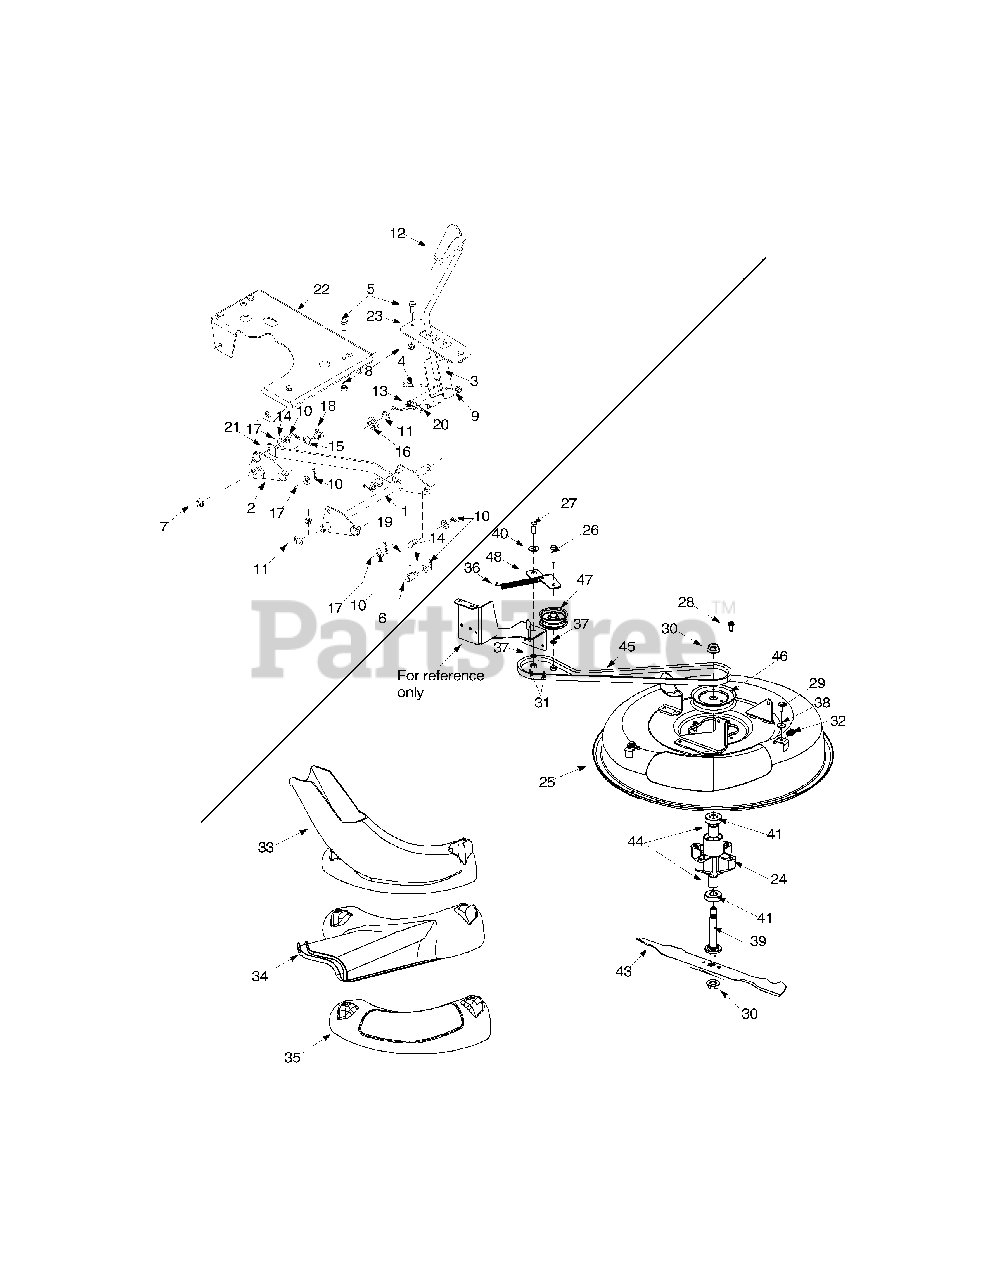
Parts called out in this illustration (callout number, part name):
1	Shift Assembly: Front Lift
2	Pivot Bracket Assembly
3	Bracket Assembly: Lift Handle
4	Hex Bolt 1/4-20 x 2.25
5	Hex Bolt M8-1.25: 20
6	Ferrule
7	Flange Lock Nut 3/8-16
8	Hex Lock Nut M8-1.25
9	Lock Nut 1/4-20
10	Hairpin Clip
11	E-Ring
12	Handle Grip
13	Torsion Spring
14	Thrust Washer .375 x .70 x .030
15	Flat Washer 5/8 x 1.0 x .030
16	Flange Washer .633 x .883
17	Flat Washer .407 x .812 x .135
18	Shoulder Screw .625 x .17: 3/8-16
19	Lift Link
20	Spacer
21	Upper Lift Link Bracket
22	Lift Hanger Bracket
23	Lift Indx. Bracket
24	Spindle Housing
26	Hex Screw 3/8-16 x 1.75
27	Hex Bolt 3/8-16 x 1.0
28	TT Screw 5/16-18 x 0.875
29	Bolt (order with #32)
30	Flange Nut 5/8-18
31	Hex Nut 3/8-16
32	Speed-Nut 5/16-18 (order with #29)
33	Grass Catcher Chute
34	Side-Discharge Chute
35	Mulch Plug
36	Extension Spring
37	Lock Washer
38	Flat Washer 8.4 x 24
39	Spindle Shaft
40	Shoulder Spacer
41	Ball Bearing
43	Blade
44	Spacer
45	Belt: V Type
46	Deck Pulley
47	Flat Idler Pulley
48	Idler Bracket: Deck
